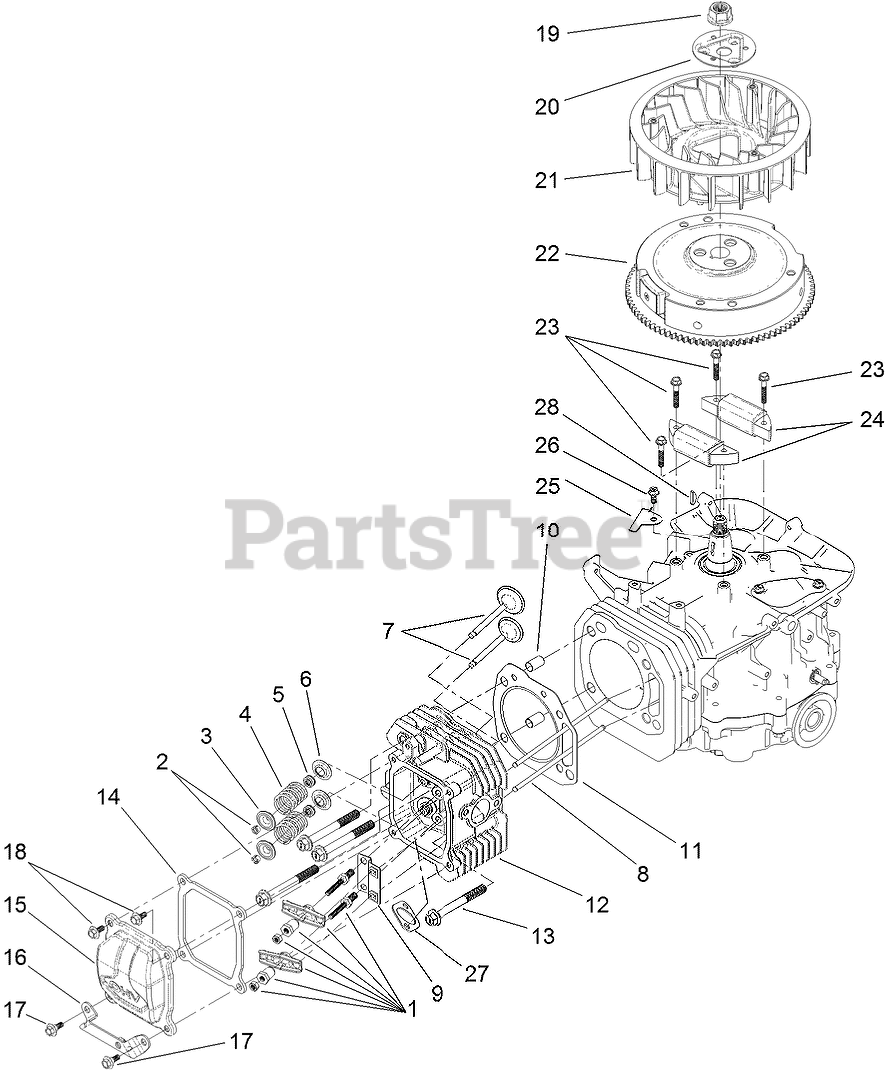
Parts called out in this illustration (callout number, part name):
1	ROCKER ARM KIT
2	KEEPER-VALVE
3	RETAINER-SPRING, VALVE
4	SPRING-VALVE
5	SEAL-STEM, VALVE
6	SEAT-SPRING, VALVE
7	VALVE SET
8	ROD-PUSH
9	PLATE-GUIDE, PUSH ROD
10	PIN-DOWEL
11	GASKET-CYCLINDER
12	HEAD-CYLINDER
13	SCREW-HHF
14	GASKET-COVER, VALVE
15	COVER-VALVE
16	BRACKET-MUFFLER
17	SCREW-SHOULDER, HHF
18	SCREW-SHOULDER, HHF
19	NUT-FLANGE
20	PULLEY-STARTER
21	FAN-COOLING
22	FLYWHEEL ASM
23	SCREW-HHF
24	COIL-CHARGE
25	RETAINER
26	SCREW-HHF
27	GASKET-EXHAUST
28	KEY-WOODRUFF
